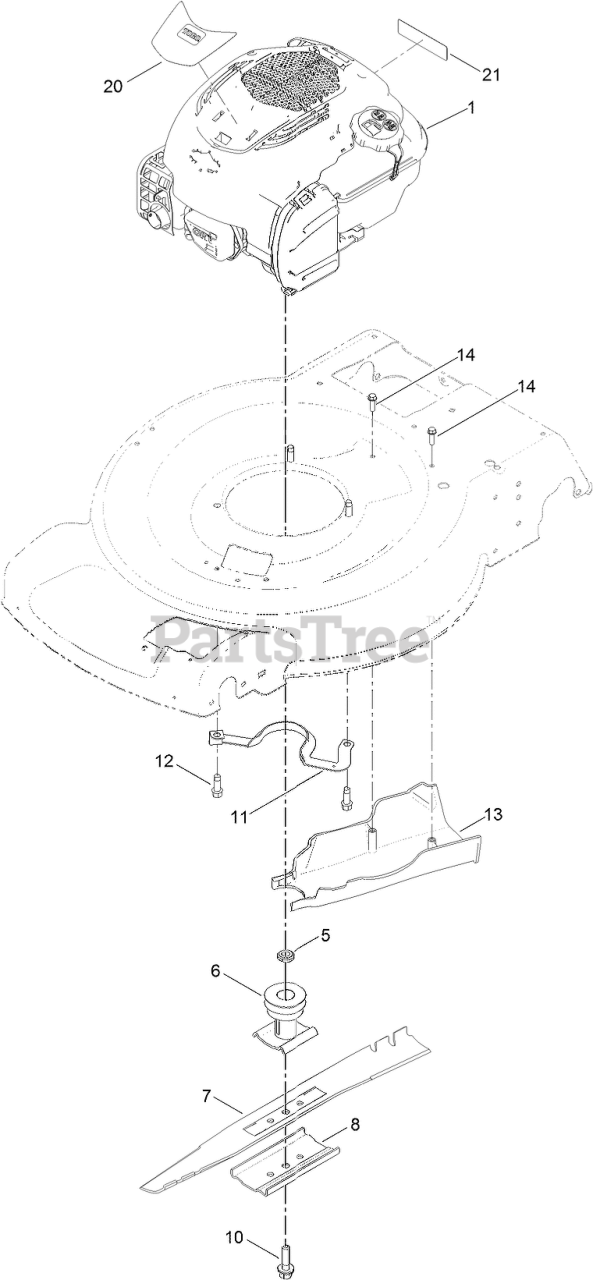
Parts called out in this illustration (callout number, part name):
5	Spacer-Driver
6	DRIVER-BLADE
7	BLADE-22 INCH
8	SUPPORT-BLADE
10	BOLT-BLADE
11	GUIDE-BELT
12	SCREW-TAPTITE
13	COVER-BELT, REAR
14	SCREW-HWH
20	DECAL-SHROUD, BRIGGS
21	DECAL-ARRESTER, SPARK
